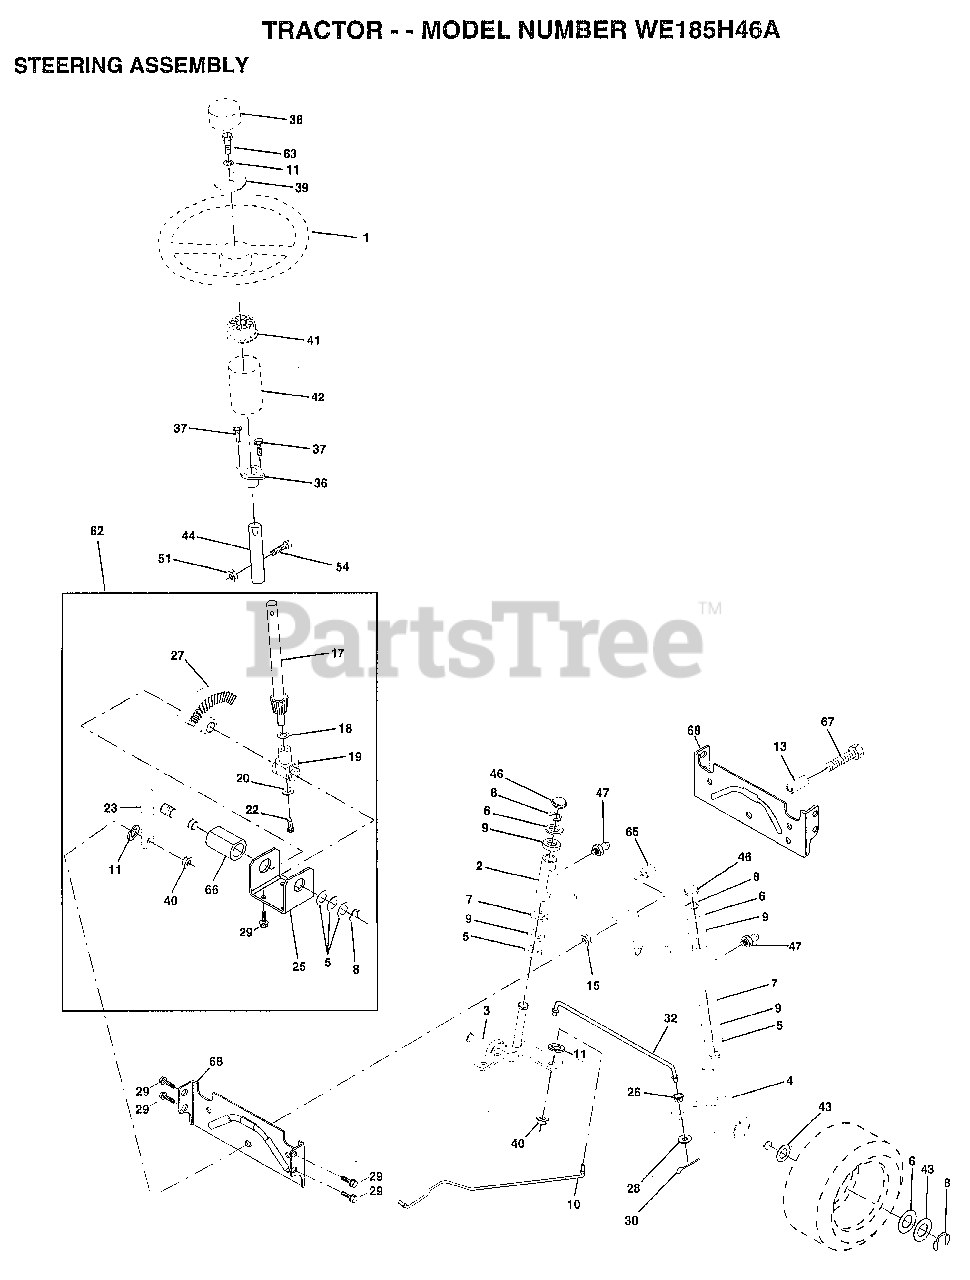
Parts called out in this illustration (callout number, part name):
1	WHEEL STR AYP BLK
2	AXLE ASM
3	SPINDLE.ASM.LH
4	"SPINDLE ASM,RH"
5	WASHER .T
6	WASHER
7	WASHER
8	RING
9	COL. SRTG. BEAR.
10	DRAGLINK-STAMPED
11	LOCKWASHER
13	BEARING AXLE
15	"NUT-LOC,FLANGE LT"
17	SHAFT ASM STEERIN
18	THRUST WASHER
19	SUPPORT.SHAFT
22	SCREW HEX SOC1/4-
25	BRKT-STEERING
26	BUSHING.DRAGLINK
27	GEAR SECTOR
28	WASHER
29	SCREW
30	COTTER PIN
32	TIE ROD
36	BUSHING.STEERING
37	"SCREW-TT,10-32 FL"
38	CAP STEER AYP
39	WASHER T
40	GRIPCO NUT
41	ADAPTER LT
42	BOOT.STEER.PL
44	EXT SHAFT STEERIN
46	CAP
47	ZERK M
51	NUT
54	BOLT
62	KIT STEERING ASM
63	BOLT
65	SPACER AXLE
66	"BEARING-ARM,PITMA"
67	BOLT
68	BRACE AXLE
